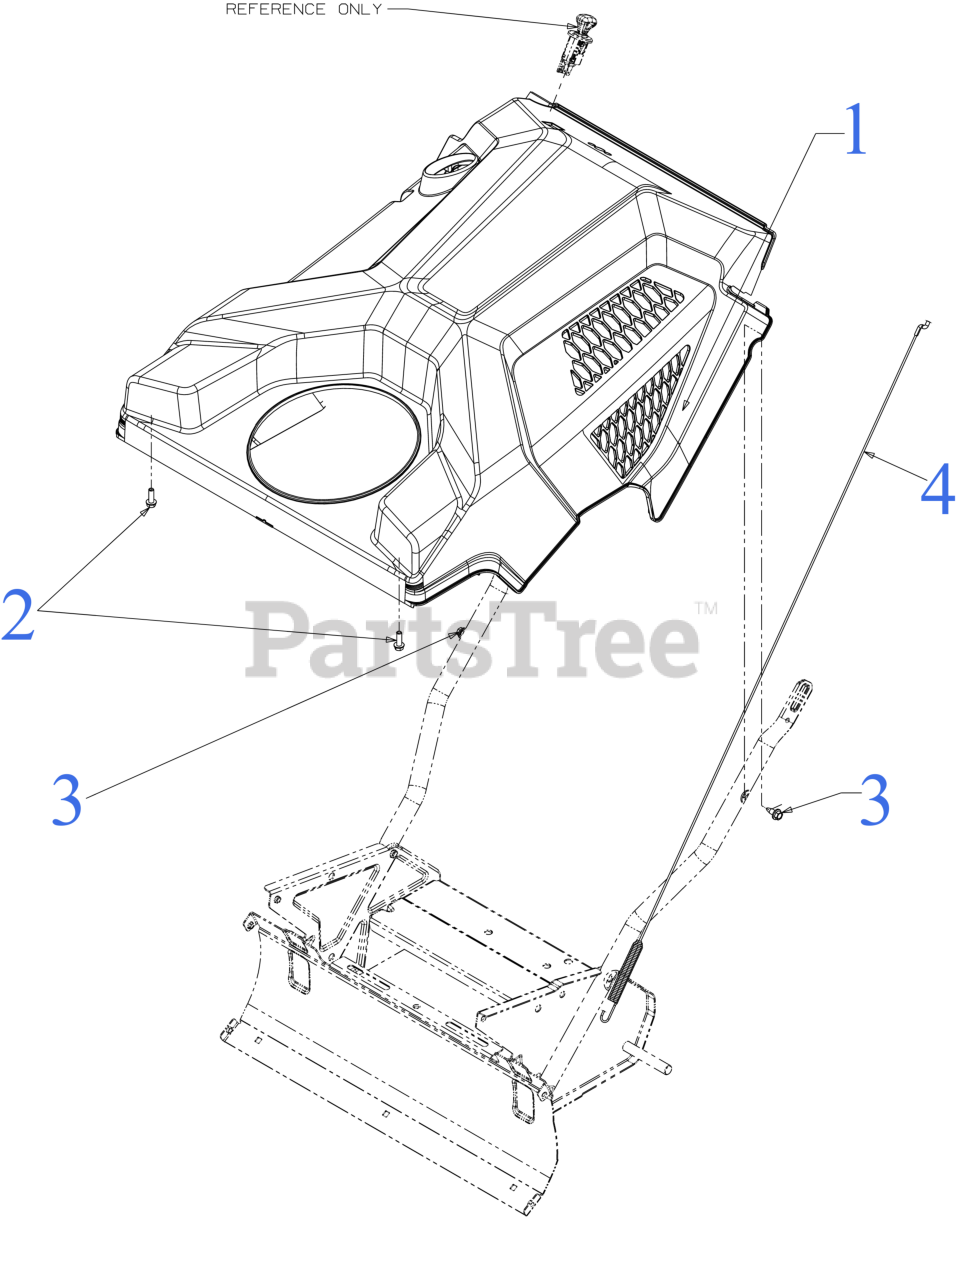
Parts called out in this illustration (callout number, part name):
1	COVER (G-STYLE) (W/O ELEC START RED)
2	SCREW 1/4-15 x .750
3	SCREW 1/4-20X.625
4	AUGER CLUTCH CABLE 37.05"
